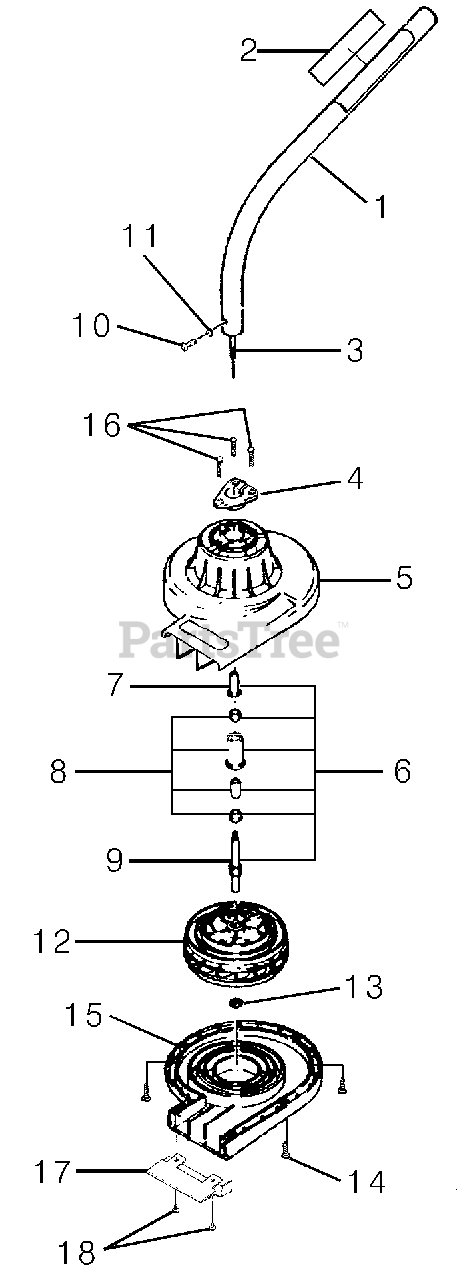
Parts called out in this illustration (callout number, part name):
1	DRIVESHAFT HOUSING
2	DECAL-Warning
3	CABLE-Flex
4	CLAMP
5	UPPER HOUSING
6	BEARING HOUSING
7	ADAPTER-Arbor
9	SHAFT-Arbor
10	SCREW (10-24 x .312")
11	WASHER, Lock (#10)
12	IMPELLER
13	CLIP
14	SCREW, Pan Hd. (8-16 x .750)
15	LOWER HOUSING
16	SCREW-Thread Forming (8-16 x 1")
17	GUARD-Lower Housing
18	SCREW (10-16 x 1/4")
